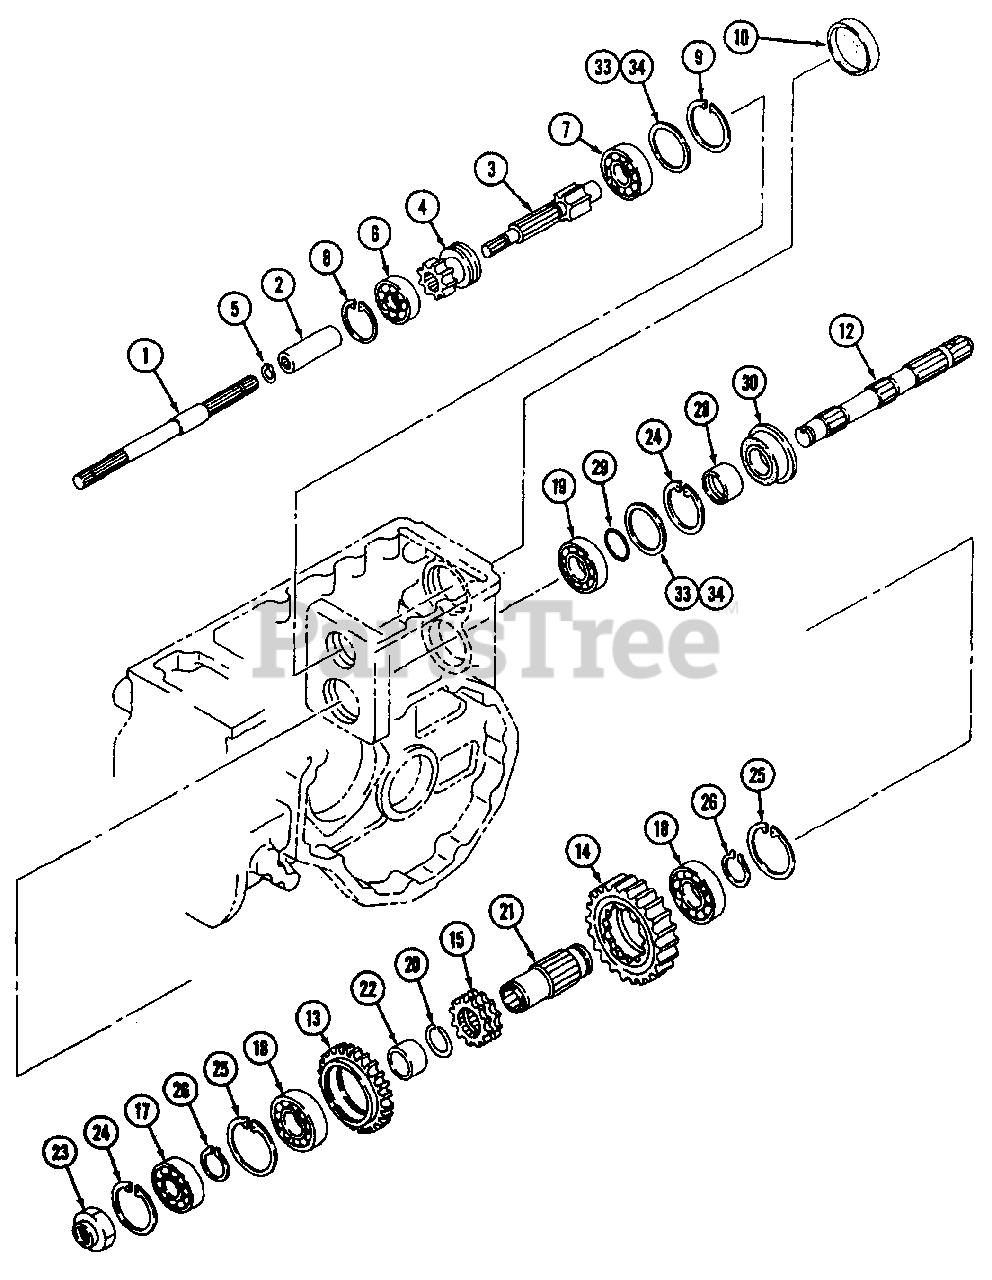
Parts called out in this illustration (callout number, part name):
3	Shaft, PTO Drive
26	Ring
30	Seal, Oil
